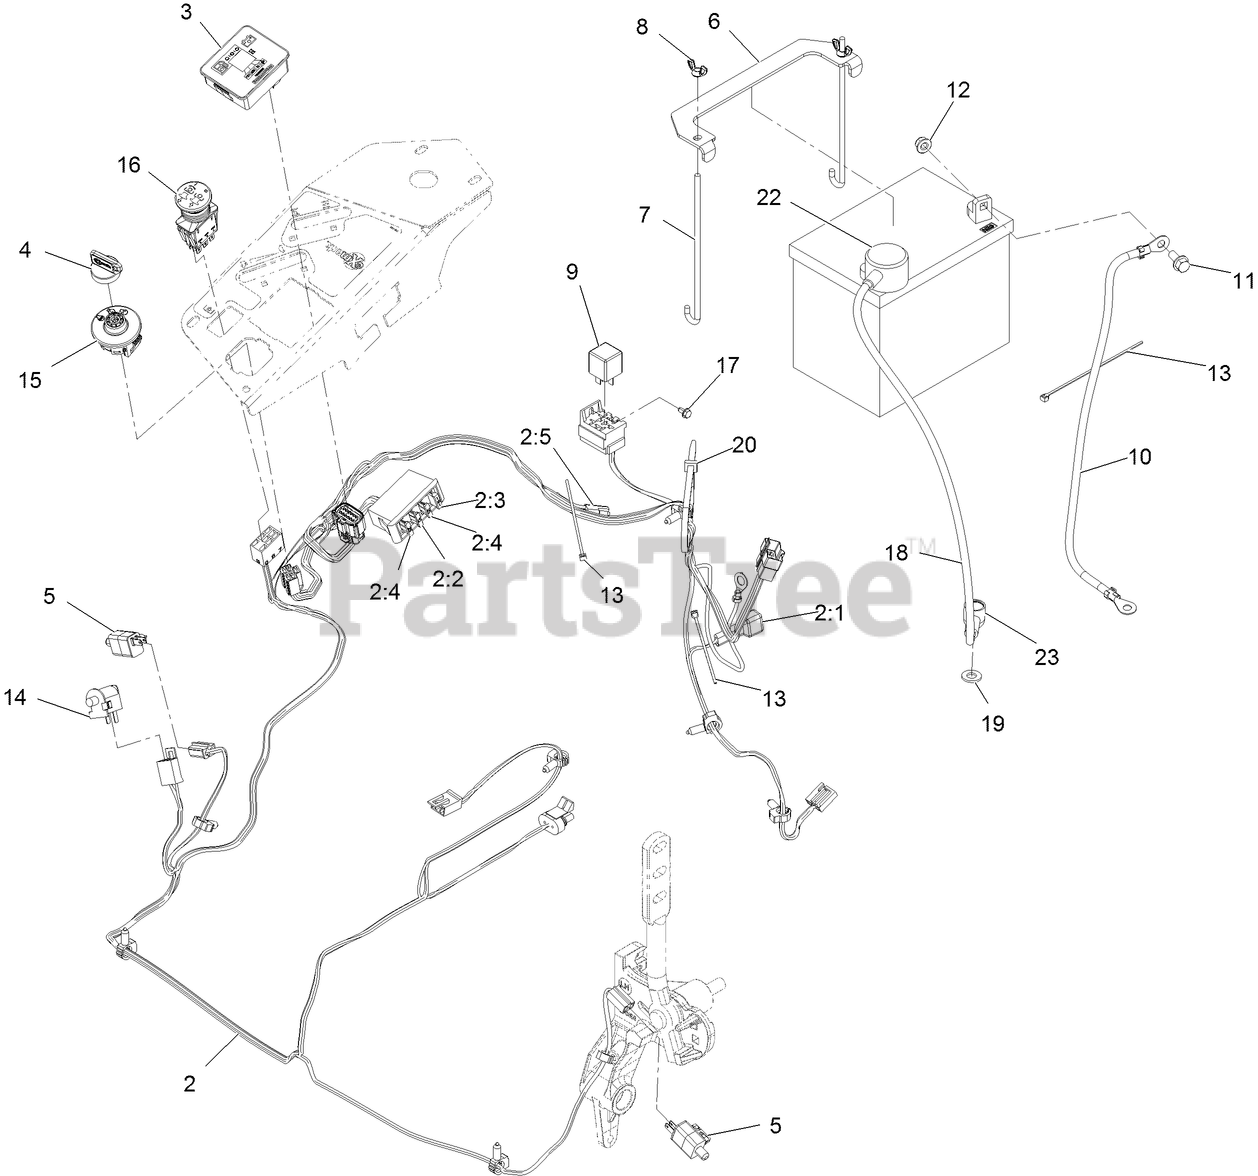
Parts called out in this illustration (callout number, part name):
2	HARNESS-WIRE, MAIN
2:2	FUSE-BLADE, 10 AMP
2:3	FUSE-BLADE, 15 AMP
2:4	FUSE-BLADE, 25 AMP
2:5	CAP-PLUG
3	FUEL/HOUR METER ASM
4	KEYS-IGNITION (SPARE PAIR
4	KEY-IGNITION
6	STRAP-TIE DOWN, BATTERY
7	BOLT-HOLDDOWN
8	WINGNUT
10	CABLE-BATTERY, NEGATIVE
11	SCREW-HHF
12	NUT-HF, NI
13	TIE-CABLE
14	SWITCH-BAIL
15	SWITCH-IGNITION
16	SWITCH, PTO 10A
17	SCREW-HWH
18	CABLE-BATTERY, POSITIVE
19	WASHER-FLAT
20	TIE-CABLE
22	INSULATOR-BATTERY
23	INSULATOR-SOLENOID
